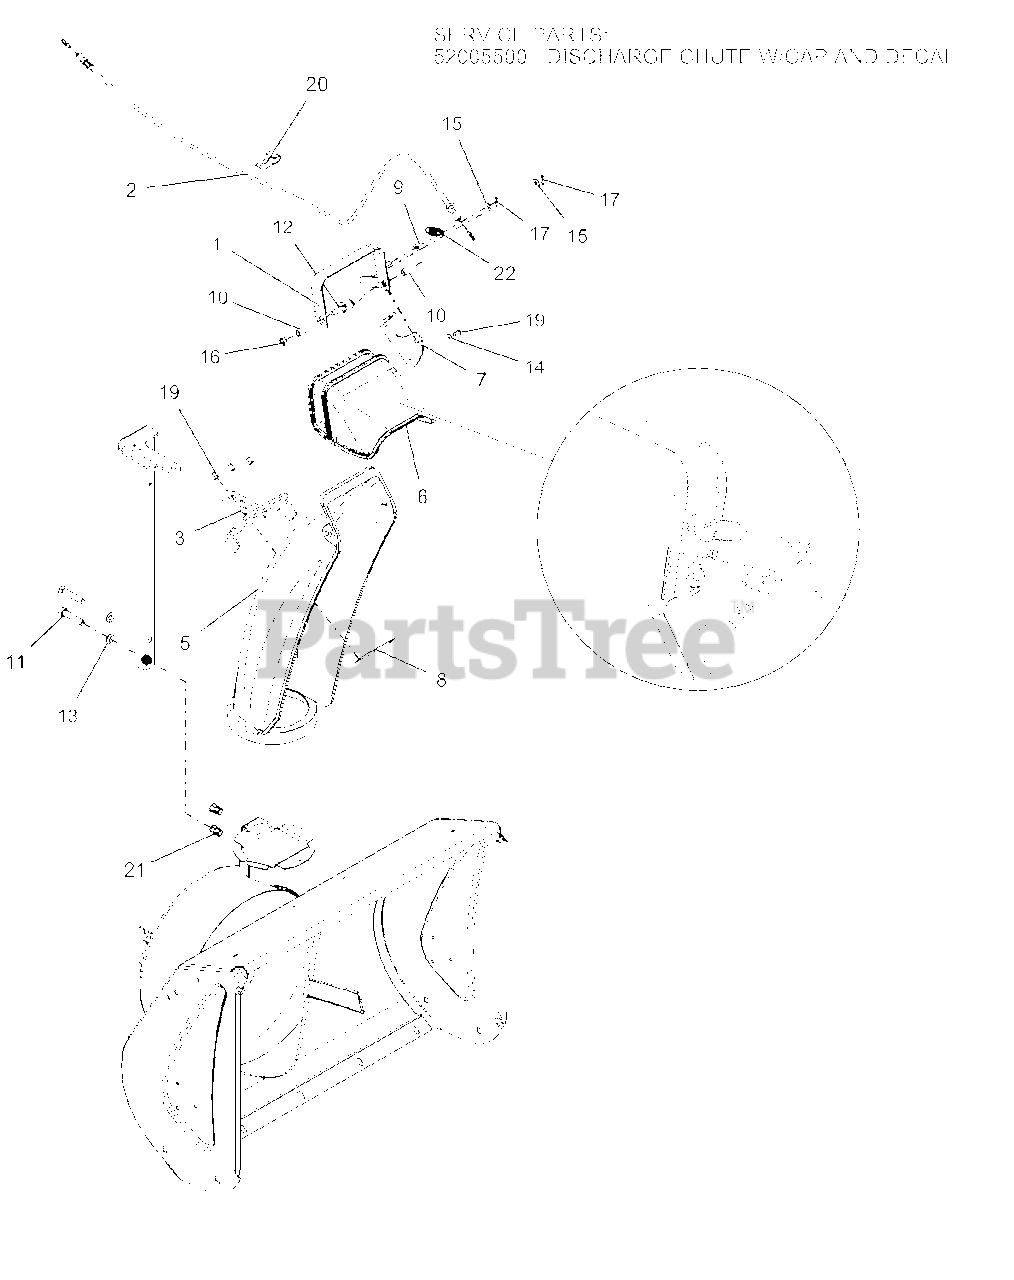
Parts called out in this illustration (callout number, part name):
1	WELDMENT, DEFLECTOR CAP SNOTEK
2	CABLE, DEFLECTOR CAP SNO-TEK
3	CHUTE MOUNT BRACKET
5	CHUTE, PLASTIC DISCHARGE LONG
6	DEFLECTOR CAP, PLASTIC
7	BRACKET, CABLE ANCHOR SNOTEK
8	PLATE,CHUTE MOUNT BACKING
9	BSHG-SLV .265X.500X.219
10	BSHG-SLV .330X.455X.550
11	@BLT-HEX .38-16X1.75 GR5 YWZC
12	BLT,RNHDRECSHNK .31-18X1.00
13	@WSHR-LK .38X.094 REG YWZC
14	WSHR-FL-STL .196X.500X.06 YZ
15	@WSHR-FL-STL.281X.62X.065 YWZC
16	@NUT-LK-CTR-JAM .31-18 YWZC
17	PIN-HAIR INT .06X.18X.77
19	RIVET, #66 STEEL POP PD BLACK
20	J-CLAMP
21	NUT, THREADED INSERT .38-16
22	SPRG, TENSION .052X.520X1.74
23	CHUTE, REMOTE DISCHARGE W/CAP
